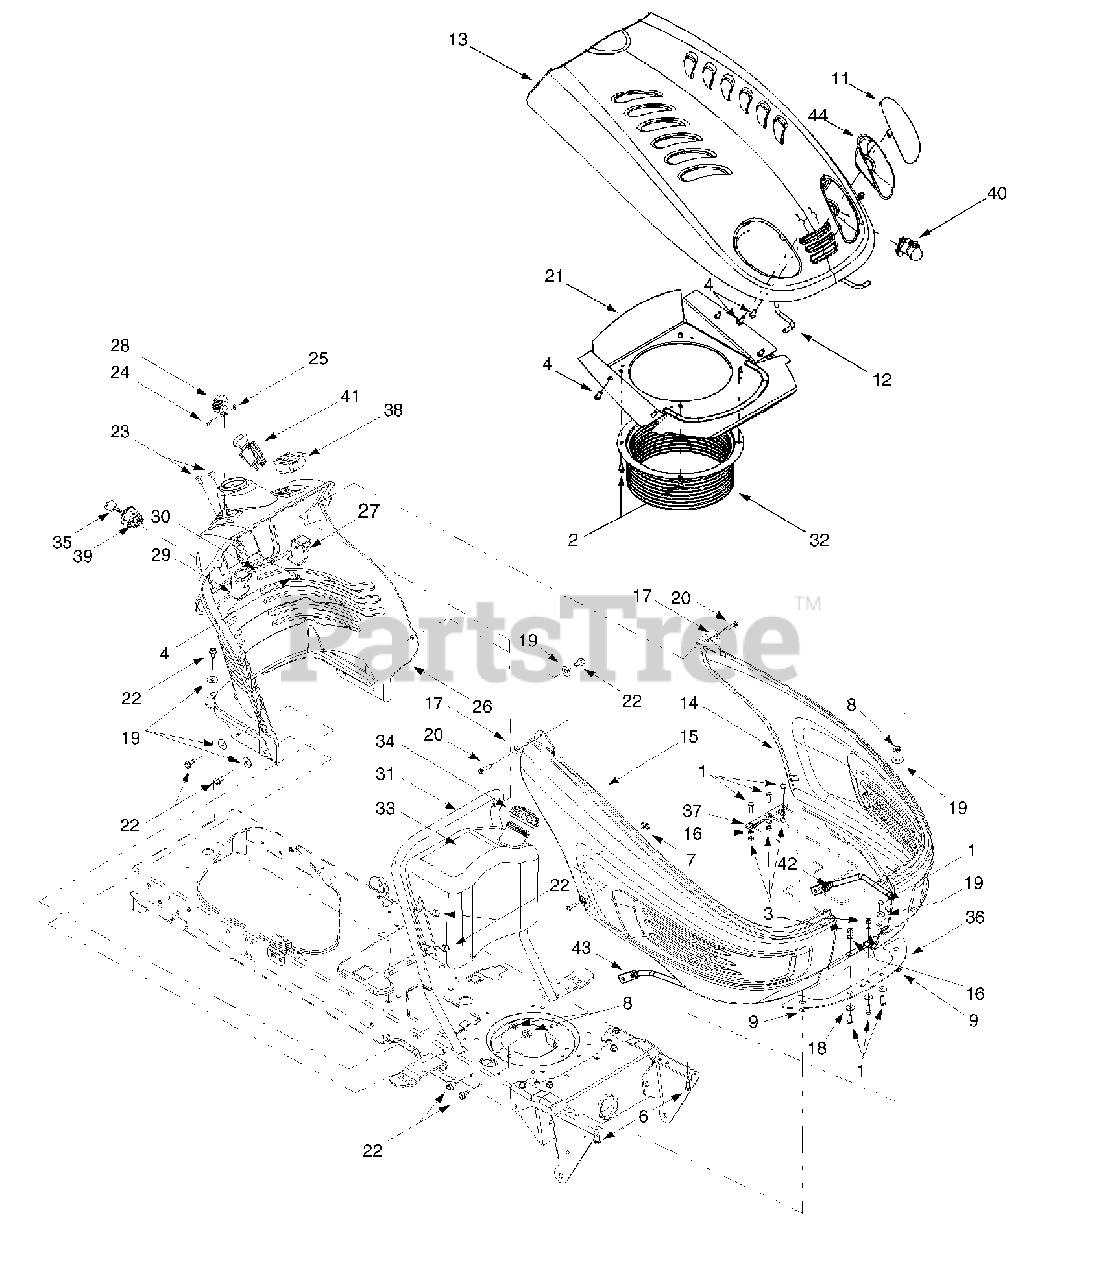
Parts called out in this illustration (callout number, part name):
1	Hex Cap Screw, 1/4-20 x .75
2	Self-tapping Screw, 1/4-20 x .5
3	Hex Nut, 1/4-20
4	Self-tapping Screw, 1/4-15 x .75
6	Hex Cap Screw, 5/16-18 x 1.25
7	U-type Speed Nut, 1/4-20
8	Flange Lock Nut, 5/16-18
9	Speed Nut
11	RH Head Light Lens
12	Hood Support Rod
13	Hood
14	LH Side Panel
15	RH Side Panel
16	Lock Washer, 1/4
17	Flat Washer, .283 x .75 x .030
18	Flat Washer, .28 x .74 x .063
19	Flat Washer, .349 x 1.0 x .063
20	Self-tapping Screw, 1/4-20 x 1.25
22	Self-tapping Screw, 5/16-18 x .625
23	Torx Self-tapping Screw, 1/4-14 x .625
24	Torx Screw, #8-32 x .375
25	Hex Nut, 8-32
26	Dash Panel, 4-style
27	Parking Brake Button
28	Throttle Control Lever
29	Cruise Control Button
30	Brake/Cruise Pivot Rod
33	Fuel Tank, 3-gallon
34	Fuel Cap
35	Ignition Key w/ plastic cover
36	Heat Shield
39	Ignition Switch
40	Headlight Assembly
41	Electric PTO Switch
